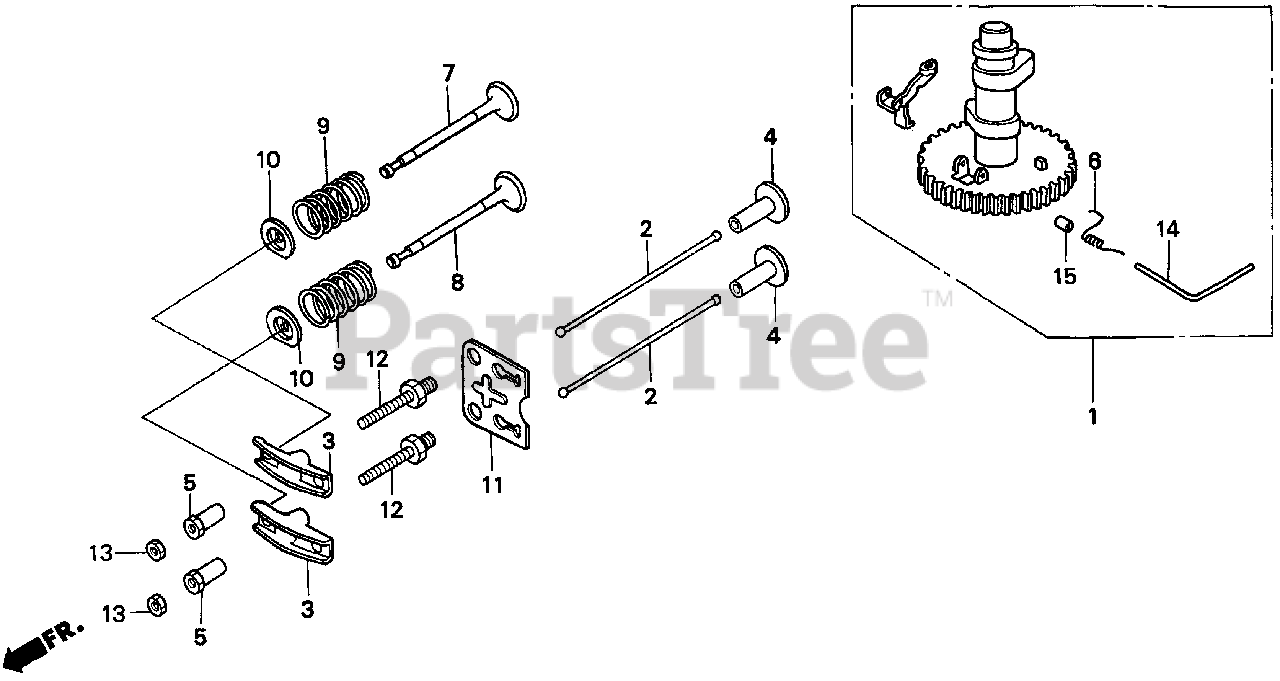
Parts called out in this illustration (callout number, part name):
1	CAMSHAFT ASSY.
2	ROD, PUSH
3	ARM, VALVE ROCKER
4	LIFTER, VALVE
5	PIVOT, ROCKER ARM
6	SPRING, WEIGHT RETURN
7	VALVE, IN.
8	VALVE, EX.
9	SPRING, VALVE
10	RETAINER, IN. VALVE SPRING
10	RETAINER, VALVE SPRING (EXHAUST SIDE)
11	PLATE, PUSH ROD GUIDE
12	BOLT, PIVOT (8MM)
13	NUT, PIVOT ADJ.
14	PIN, WEIGHT CENTER
15	COLLAR, WEIGHT CENTER
